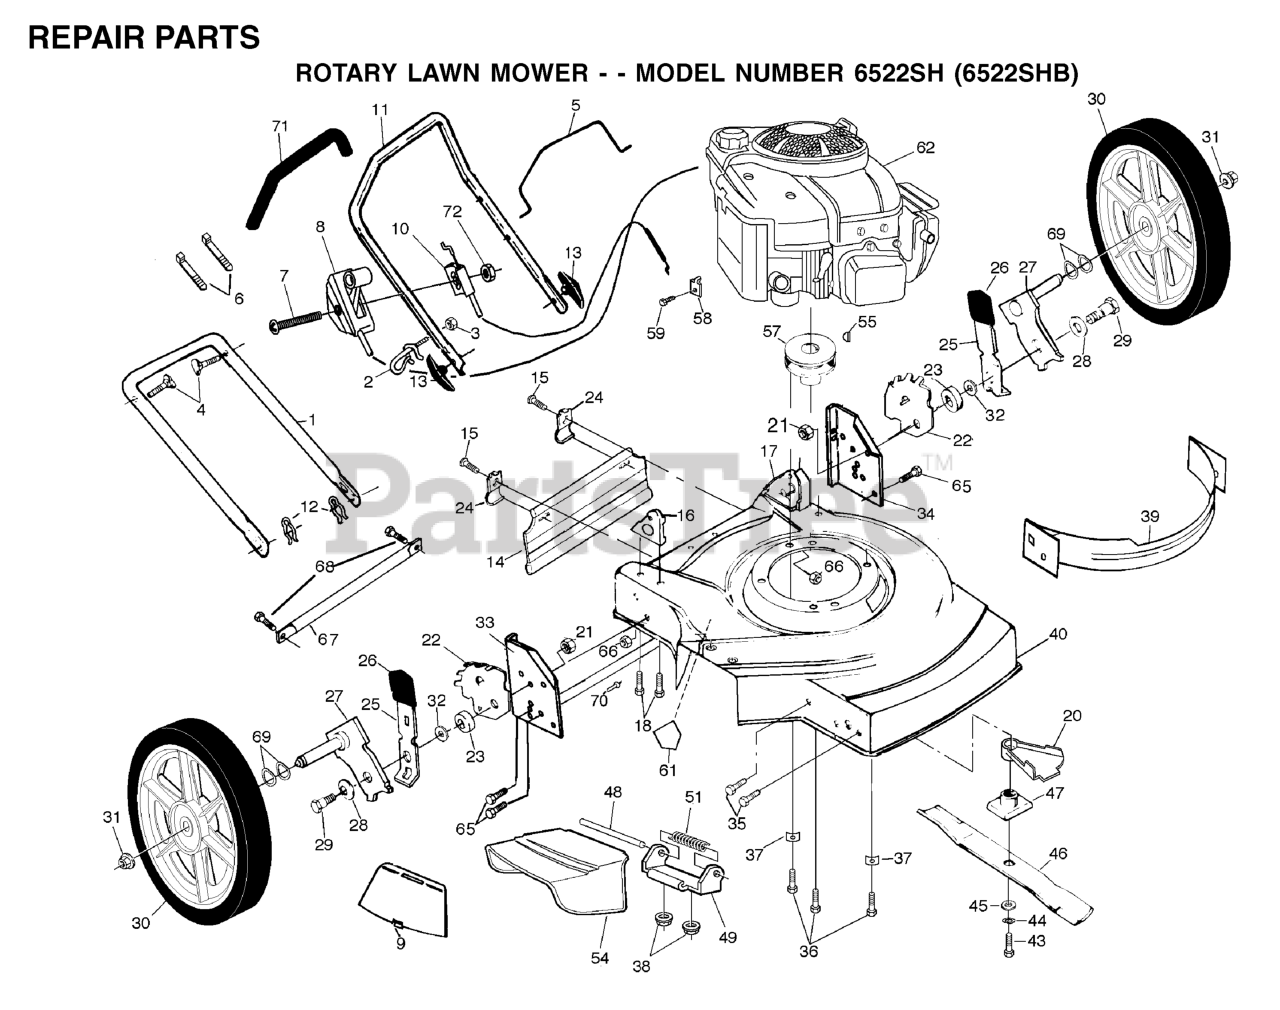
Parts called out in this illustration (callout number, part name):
1	LOWER HANDLE
2	ROPE, GUIDE
3	NUT
4	HANDLE BOLT
6	TIE GUIDE
7	SCREW 1/4-20 X 2.12
8	THROTTLE CONTROL
9	REPL BY 532 12 54-20
10	CABLE.MZR.51.RT.SP./PU.
11	UPPER HANDLE
12	HAIRPIN COTTER
13	HANDLE KNOB
14	REAR SKIRT
15	TAPPING SCREW
16	HANDLE BRACKET ASM. RH
17	HANDLE BRACKET ASM. LH
18	SCREW.5/16-18X3/4
20	DEBRIS SHIELD
21	LOCKNUT PM
22	WHEEL ADJ BRKT
23	RP SPACER HT ADJ
24	BRACKET DEFL PM
25	SELECTOR SPRING
29	BOLT
31	HEX FLANGE LOCKNT
32	WASHER.FLAT.1/2
35	SCREW 1/4X20
36	BOLT 3/8-16X1-1/8
37	WASHER.ENGINE.BZP
38	NUT
39	FRONT BAFFLE KIT
43	SCREW, HEX HD 3/8-24 X 1-3/8
44	LOCKWASHER
45	WASHER,HARDEN
47	BLADE ADAPTOR
48	ROD.HINGE.COMBI-C
49	BRACKET PM
54	DISCHARGE GUARD
55	HI PRO KEY PM WSL
57	ENGINE.PULLEY.FWG
58	WASHER
59	SCREW.HEX.HEAD.WASHER.10-16
61	DECAL HYT
66	LOCKNUT PM
69	WAVE WASHER
70	RIVET BLIND
71	GRIP.HANDLE.FOAM
72	NUT
